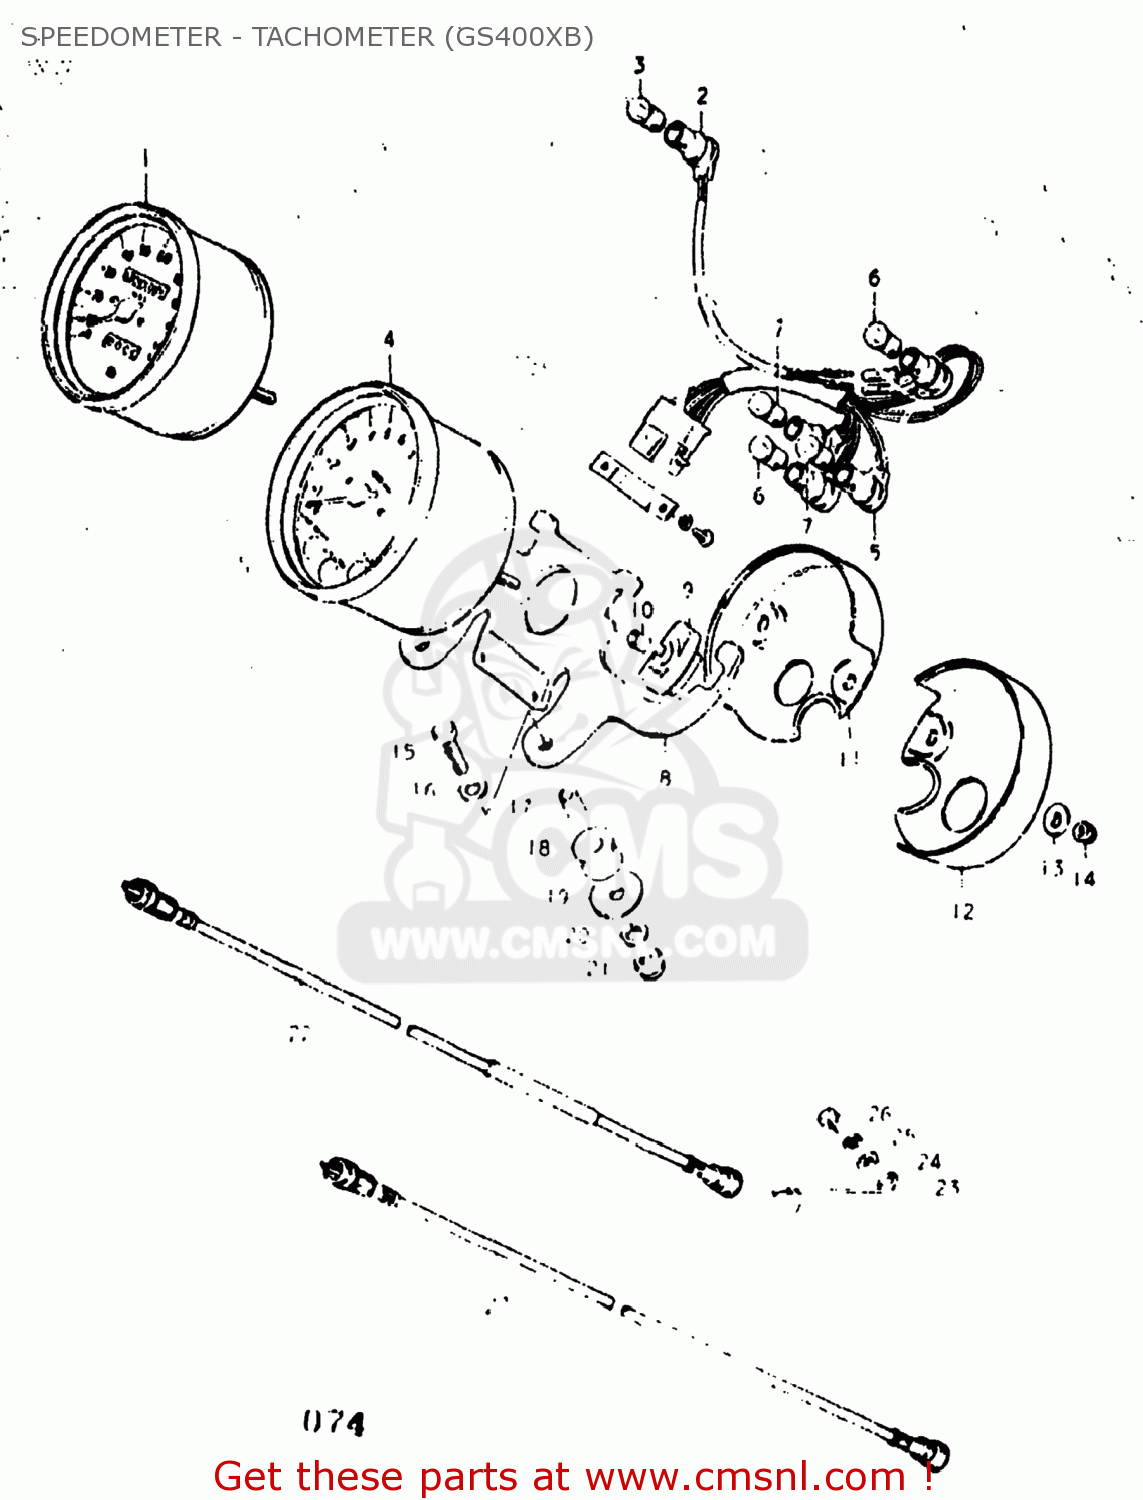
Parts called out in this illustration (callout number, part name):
1	SPEEDOMETER ASSEMBLY
2	SOCKET,METER
3	BULB(12V3.4W,STANLEY,A72A)
4	METER,TACHOMETER
5	SOCKET,TACHOMETER
6	BULB(12V3.4W,STANLEY,A72A)
7	BULB(12V1.7W,A71A)
8	BRACKET,METER
9	CUSHION,METER
10	SPACER,METER
11	PANEL,METER
12	COVER,METER,UNDER
13	WASHER,METER
14	NUT
15	BOLT
16	WASHER
17	SPACER (6.1X9X9)
18	CUSHION,METER
19	WASHER (6.5X20X1.2)
20	LOCK WASHER
21	NUT
22	CABLE ASSEMBLY,SPEEDOMETER
23	GUIDE,SPEEDOMETER CABLE
24	WASHER 6MM
25	LOCK WASHER
26	BOLT
27	CABLE ASSEMBLY,TACHOMETER
